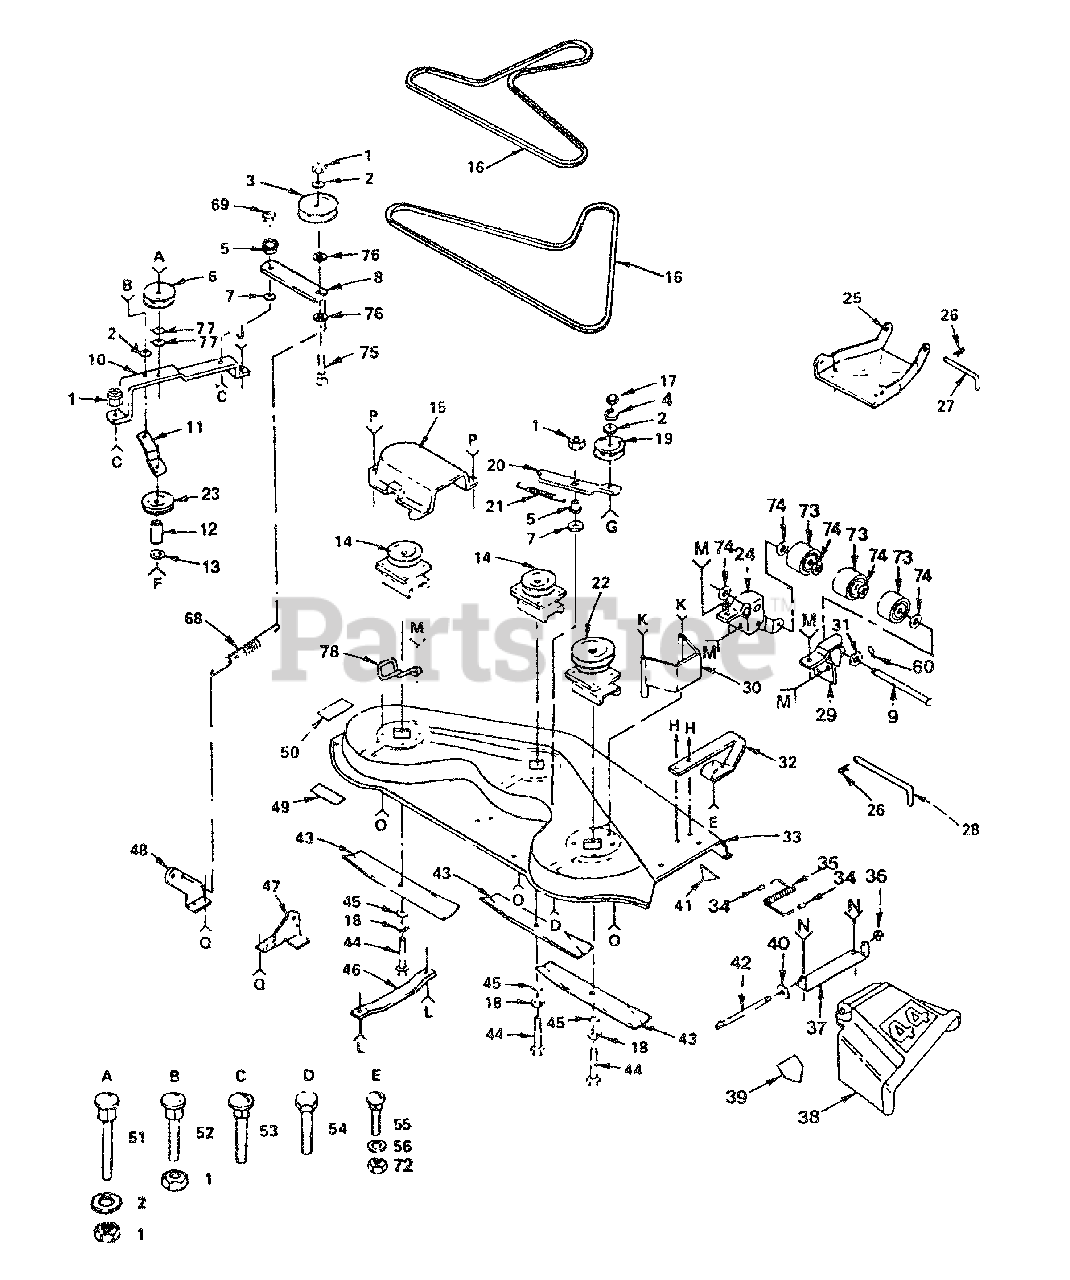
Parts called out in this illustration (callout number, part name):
1	Nut-Lock 3/8-16
2	Washer 13/32 x 1 x 14 Ga.
3	Pulley Idler
4	Washer, Lock 3/8
6	Pulley Idler
7	Washer-Wear
10	Bar-Support-Idler
11	Brace Idler-Deck
13	Washer, 13/32 x 13/16 x 16 Ga.
14	Mandrel-Secondary
17	Nut, Hex 3/8-16
18	Washer Lock 3/8
19	Idler Flat
20	Arm-Idler-Deck
21	Spring Extension
22	Mandrel-Primary
23	Pulley, Idler
24	Bracket Lift- L.H.
25	Link Parallel
26	Retainer-Spring
27	Pin, Front Hinge
28	Pin, Rear Hinge
29	Bracket Lift-R.H.
30	Guard-Belt-R.H.
31	Washer 15/32 x 1 x 16 Ga.
32	Runner, R.H.
33	Housing-Mower
34	Cap Sleeve
35	Spring
37	Bracket-Deflector
38	Guard-Discharge
39	Decal Warning
40	Washer 11/32 x 5/8 x 16 Ga
41	Decal, OPEI (not serviced)
43	Blade, Mower
44	Bolt, Hex 3/8- 24 x 1-1/2 Gr. 5
45	Washer 13/32 x 1-1/4 x 12 Ga.
46	Runner L.H
47	Bracket-Suspension Rear- R.H.
48	Bracket-Suspension Rear- L.H.
49	Decal -V-Belt Schematic
50	Instruction Caution Decal
51	Bolt-Carriage 3/8-16 x 1-3/4
52	Bolt-Carriage 3/8-16 x 1
53	Bolt-Carriage 3/8-16 x 1-1/2
54	Bolt, Hex 3/8-16 x 1-1/4
55	Bolt-Carriage 5/16-18 x 3/4
56	Washer 11/32 x 11/16 x 16 Ga.
60	Pin, Cotter
68	Spring Extension
69	Nut-Centerlock 3/8-16
72	Locknut 5/16-18
73	Roller-Nose
74	Washer 15/32 x 1 x 10 Ga.
75	Bolt-Carriage 3/8-16 x 2-1/2
76	Washer 13/32 x 3/4 x 10 Ga.
77	Washer 13/32 x 7/8 x 10 Ga.
78	Keeper-L.H. Mandrel
